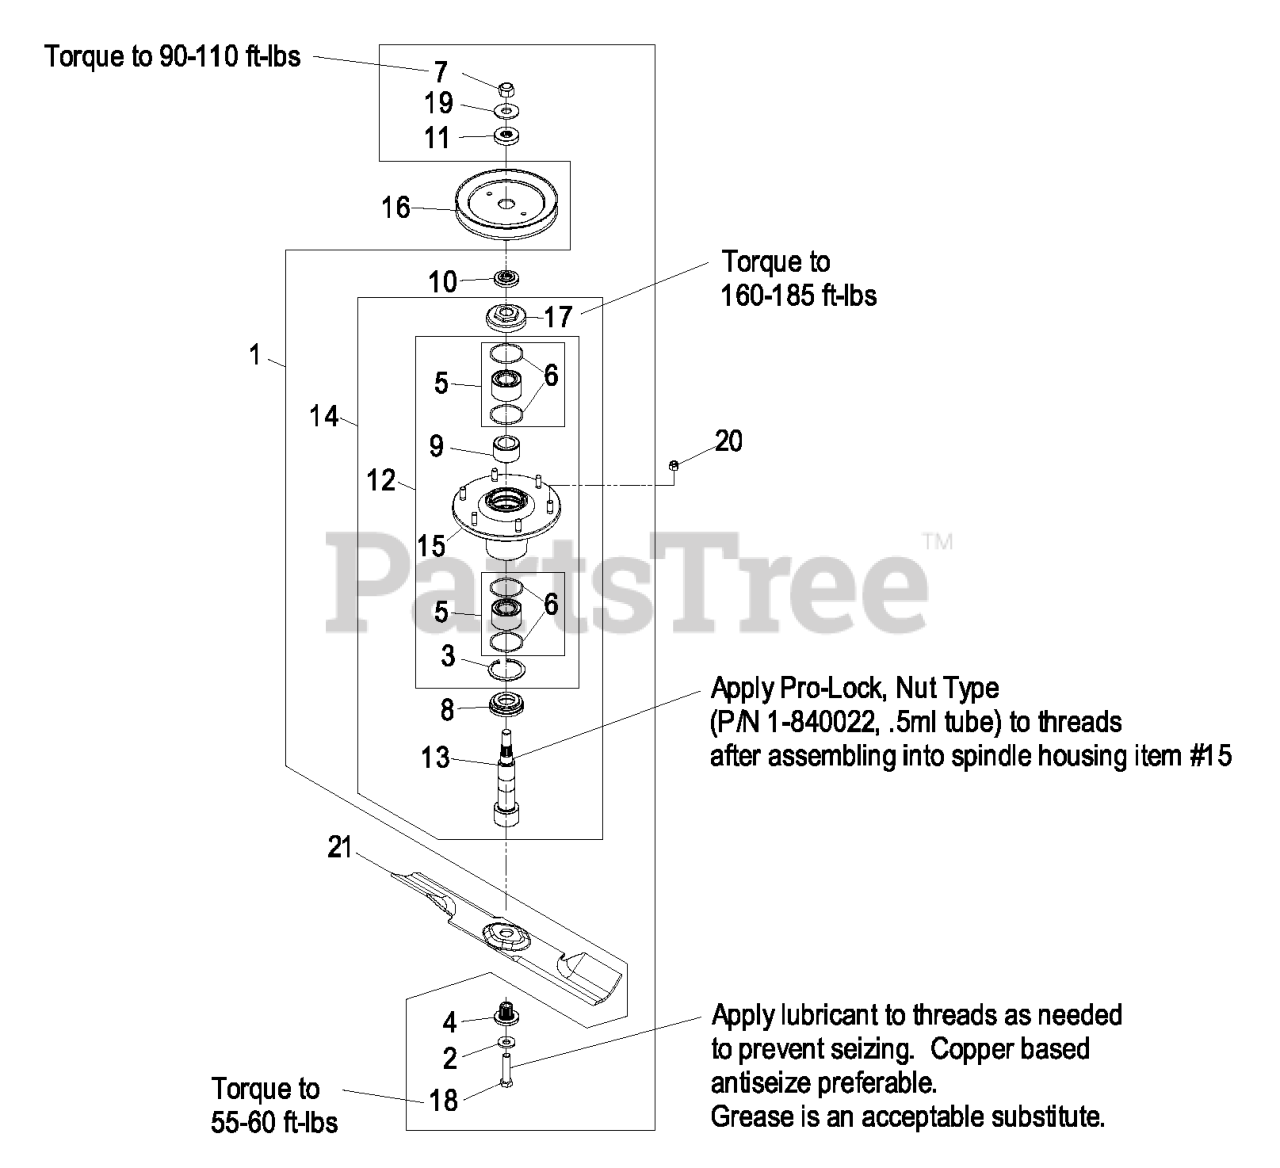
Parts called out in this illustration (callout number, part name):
1	ASM, CUTTER HSG W/MNT HRD
2	WASHER-SPRING
3	RING-RETAINING
4	BUSHING,SPLINED
5	ASM, BEARING W/ORINGS
7	NUT-LOCK NI
8	GUARD,BOTTOM
9	SPACER,BEARING
10	SPACER,SPLINED STEPPED
11	SPACER,SPLINED
12	ASM,CUTTER HOUSING
15	ASM,HOUSING W/STUDS
16	SHEAVE,BLADE DRIVE 6.75
18	SCREW-HH
19	WASHER-FLAT
20	NUT-LOCK, NI
